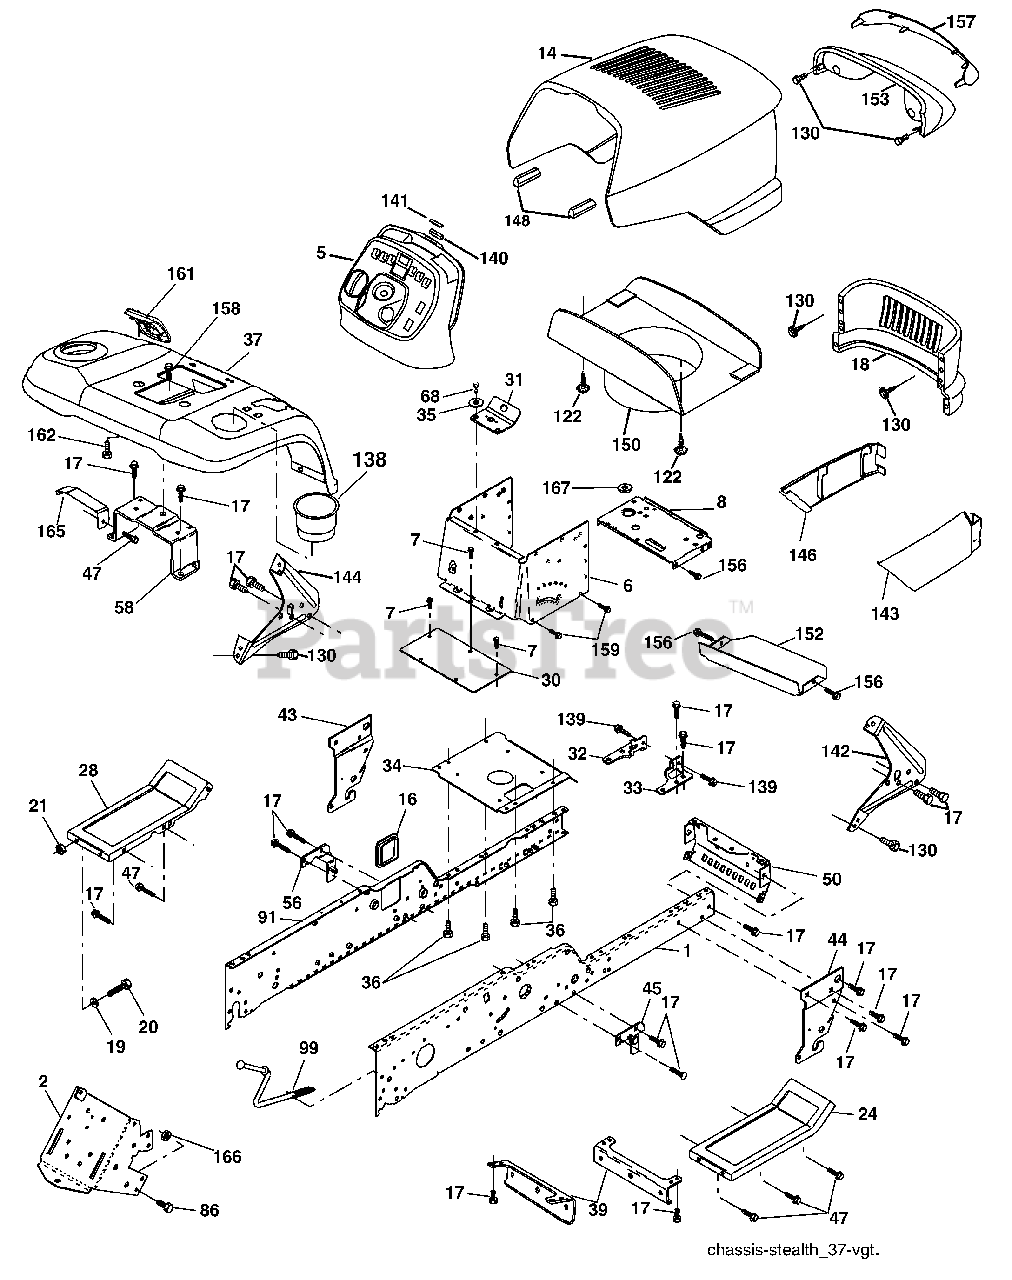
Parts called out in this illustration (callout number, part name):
1	Rail, Frame RH
2	Drawbar, Gt
5	Dash
6	Dash Asm., Lower
7	Screw, Thd Cut 1/4-20 x 1/2
8	Support, Battery
14	Hood Asm., Pnt
16	Cover, Access
17	Screw, 3/8-16 x 3/4
18	Grille
19	Washer 13/32 x 13/16 x 12 Ga.
20	Bolt, Fin Hex 3/8-16 x 1
21	Nut, Lock Hex w/Ins. 3/8-16 Unc
24	Footrest, RH
28	Footrest, LH
30	Saddle, Hydro 1995
31	Bracket, Supt 1-pc VGT Steering
32	Bracket, Pivot Chassis LH
33	Bracket, Pivot Chassis RH
34	Plate Asm. Engine Chassis
35	Washer 11/32 x 11/16 x 16 Ga.
36	Screw 5/16-18 x 3/4
37	Fender, Pnt.
39	Bracket, Axle Front
43	Bracket, Spnsn Front Lh
44	Bracket, Spnsn Front Rh
45	Bracket Asm., Susp Chassis Rh
47	Screw Thdrol 3/8-16 x 1/2 TYT
50	Bracket, Chassis Front
56	Bracket Asm., Susp Chassis Lh
58	Bracket Asm., Fender
68	Screw, Thd 5/16-18 x 1/2
86	Bolt, Fin Hex 7/16-14 Unc x 1
91	Rail, Frame Lh
99	Rod By Pass
122	Screw Hex Wshd 8-18 x 7/8
130	Screw HWHD Hi-Lo #13-16 x 3/4
138	Cupholder YTGT
139	Bolt Shoulder 5/16-18 TT
140	Magnet YTGT
141	Stricker Plate YTGT
142	Bracket Dash RH
143	Skirt Grill RH
144	Bracket Dash LH
146	Skirt Grill LH
148	Extrusion Bumper
150	Duct Heat Hood
152	Shield Browning
153	Light Box Asm. w/Lens
156	Screw 5/16-18 x 3/4
157	Lens, Bar
158	Screw Thdrol 3/8-16 x 1/2
159	Screw 3/8-16 x 3/4
161	Console Fuel Window
162	Screw 1/4-1/2
165	Bracket Support Tank
166	Nut, Crownlock 7/16-14Unc
167	Bushing
